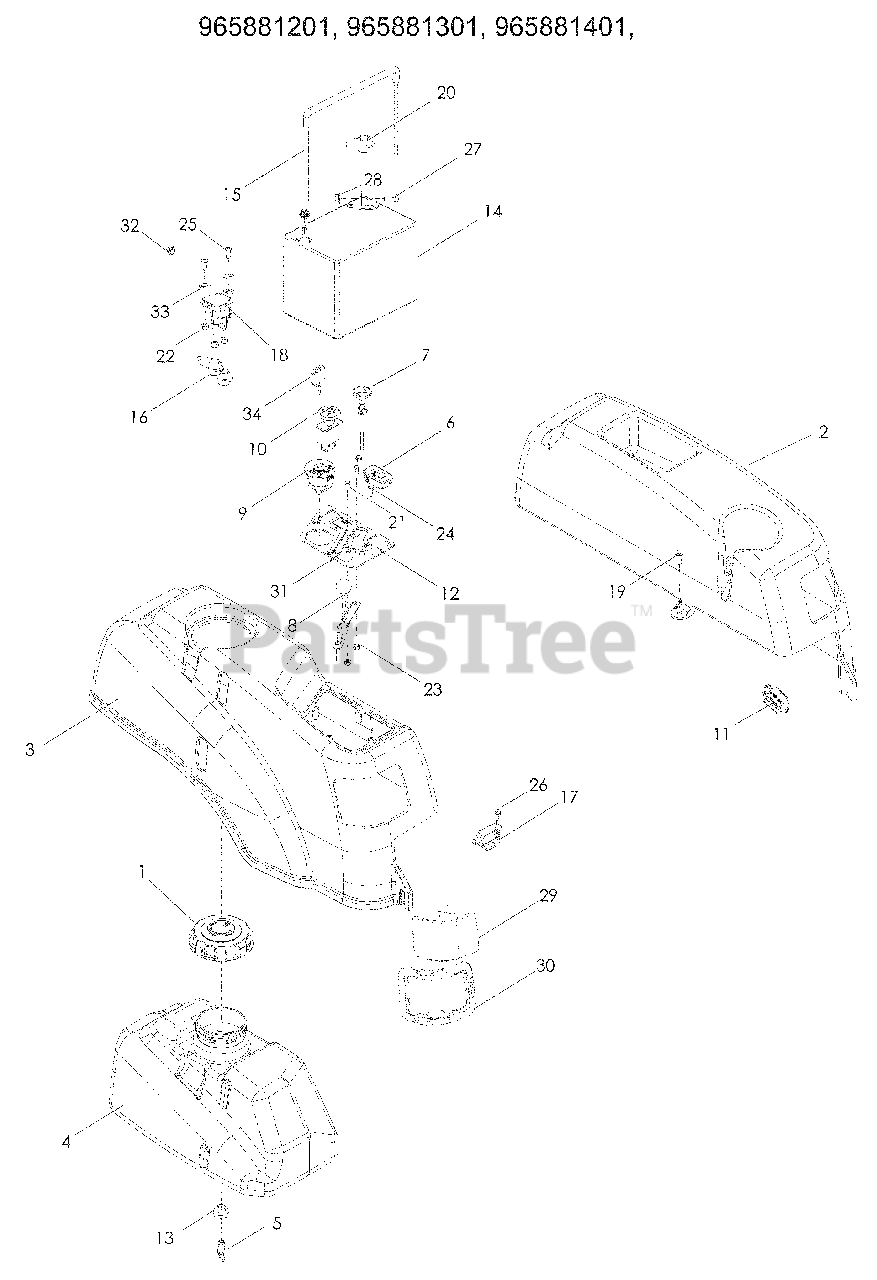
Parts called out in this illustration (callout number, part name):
2	FENDER, LT
3	FENDER, RT
4	TANK, FUEL
5	ELBOW, TANK
6	HOUR METER
7	CONTROL, CHOKE
8	CABLE, THROTTLE
9	SWITCH, IGNITION
10	SWITCH, CLUTCH
11	SWITCH, BRAKE
12	PLATE, CONTROL
13	GROMMET, RUBBER
14	BATTERY
15	TIE DOWN, BATTERY
16	COVER, TERMINAL
17	SWITCH, N.C.
19	BOLT ¼-20 x ½ HWST
20	COVER, TERMINAL
21	SCREW 10-24 x ½ SLT HD
22	NUT ¼-20 HEX NYLOC
23	NUT 10-24 HEX NYLOC
24	SCREW 10-12 x ¾ WSHR HD
25	SCREW ¼-20 x 5/8 BTN SKT
26	SCREW 10-24 x 5/8 WSH HD
27	RHSNB 5/16-18 x ¾
28	NUT 5/16-18 FLANGE NYLOC
29	LENS, LT
30	LENS RIM, LT
31	DECAL, CONSOLE
32	NUT ¼-20 HEX NYLOC THIN
33	WASHER ¼ ITLW
34	KEY, IGNITION
